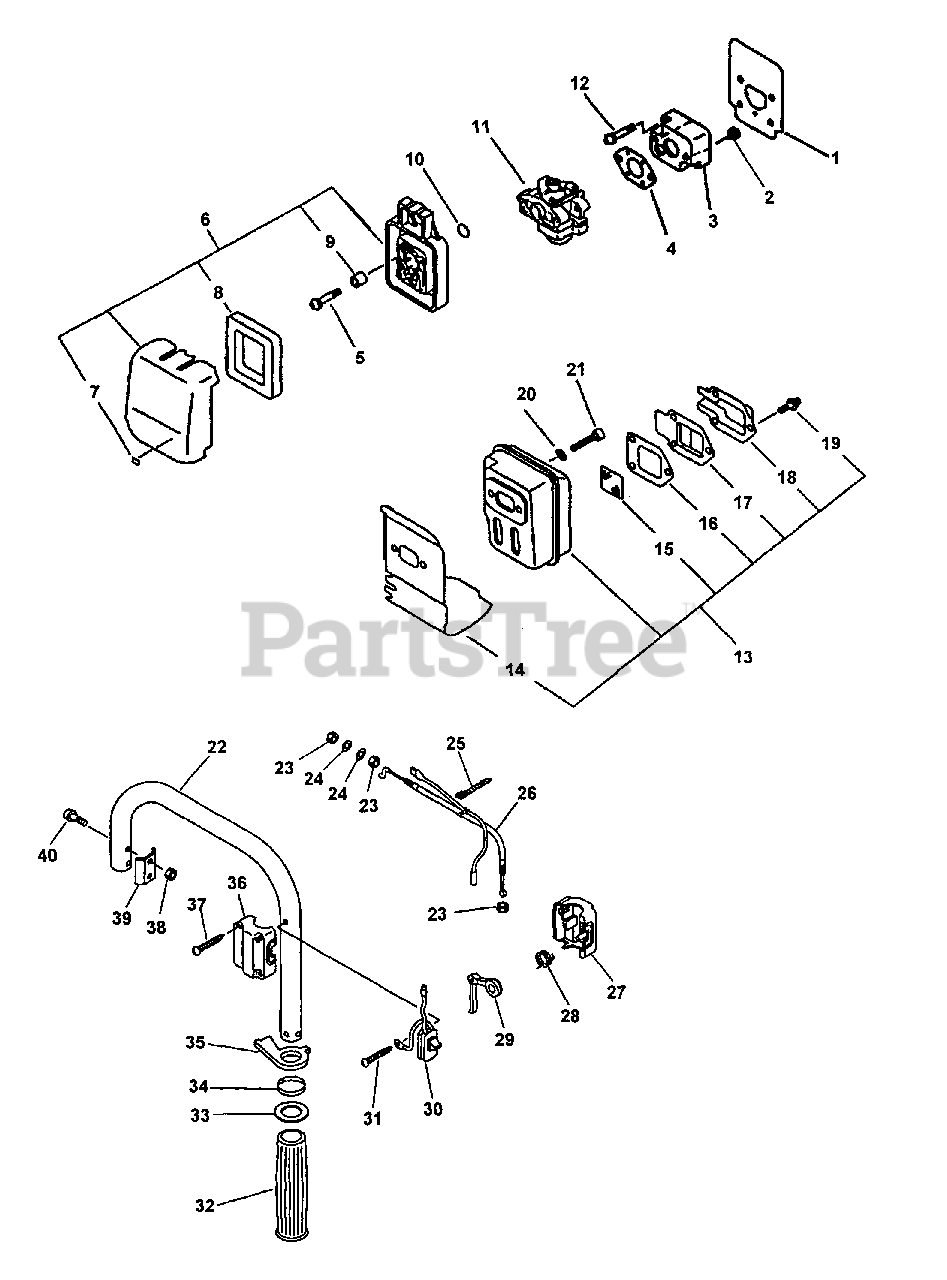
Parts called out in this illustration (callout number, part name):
1	SHIELD, INTAKE
3	INSULATOR, INTAKE
4	GASKET, INTAKE
5	SCREW - 5X64
6	AIR CLEANER ASSY
8	FILTER, AIR
9	SLEEVE
10	O-RING - 15
11	CARBURETOR WYL-23
11	CARBURETOR WYL-53
12	SCREW - 5X20
13	MUFFLER ASSY
14	GASKET, EXHAUST
15	SCREEN, SPARK ARRESTOR
16	GASKET, EXHAUST
17	GASKET, EXHAUST - INNER
18	GUIDE, EXHAUST
19	SCREW - 4X10
20	WASHER - 5
21	SCREW - 5X55
22	HANDLE - REAR
24	WASHER - 6
25	TIE, CABLE
26	CABLE, THROTTLE
26	CONTROL CABLE ASSY
27	BRACKET, THROTTLE CONTROL - RIGHT
28	SPRING, TRIGGER
29	TRIGGER, THROTTLE
30	IGNITION SWITCH ASSY
31	SCREW - 4X30
32	GRIP, HANDLE - RIGHT
33	SPACER
34	SPRING, LOCKOUT LEVER
35	LEVER, TRIGGER LOCKOUT
36	BRACKET, THROTTLE CONTROL - LEFT
37	SCREW - 4X25
38	LOCKNUT - 5
39	PLATE, HANDLE
40	SCREW - 5X35
